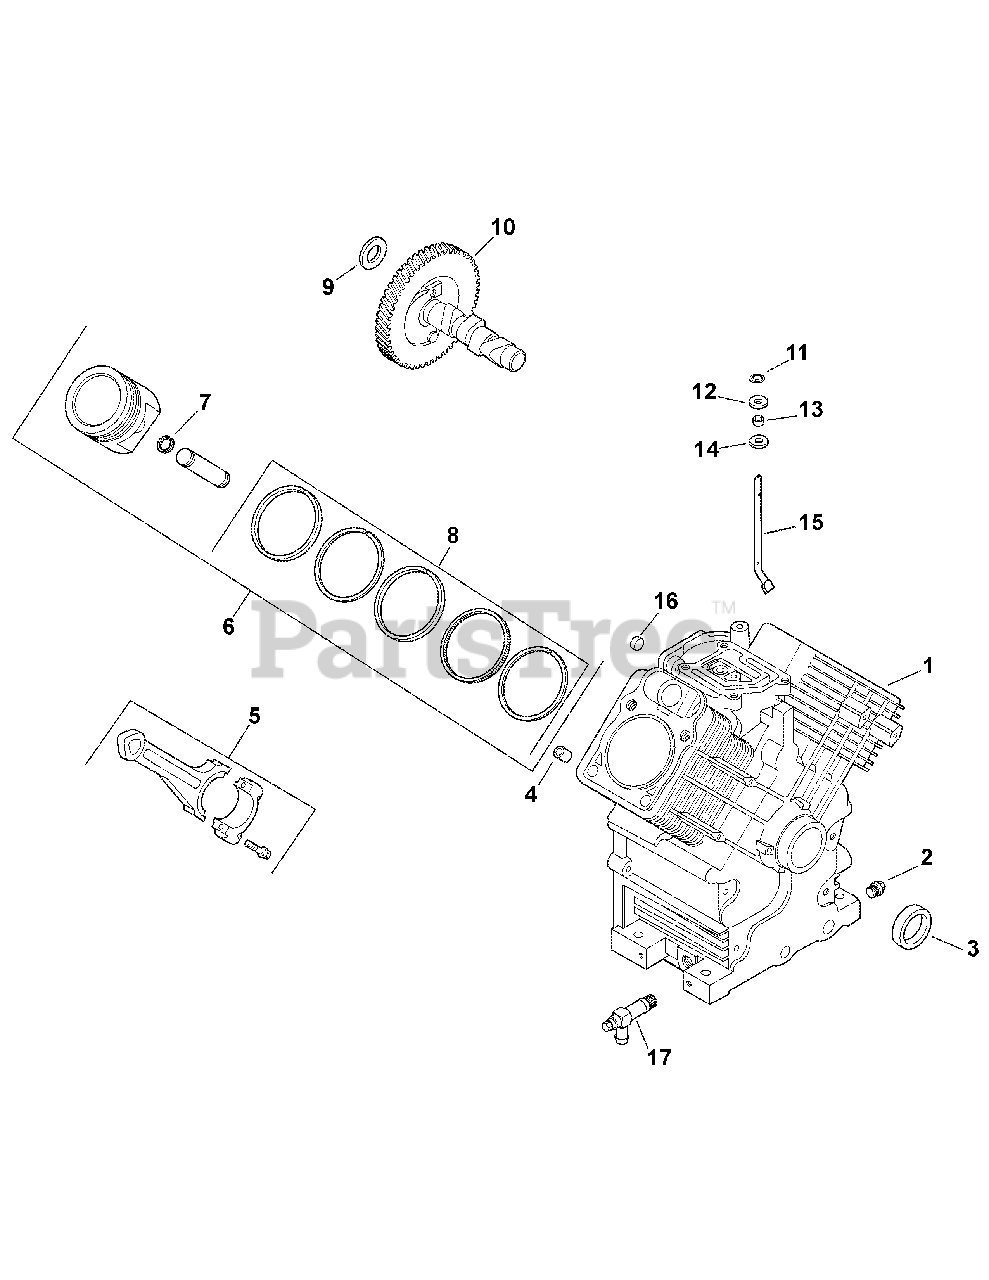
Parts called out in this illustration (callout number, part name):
1	Crankcase
1	Engine, Complete
2	Plug, sq. head 3/8" (2)
3	Seal, front oil
4	Pin, locating (6)
5	Connecting Rod (Std.) (2)
5	Connecting Rod (.25) (2)
6	Piston w/Ring Set (Std.) (2)
6	Piston w/Ring Set (.08) (2)
6	Piston w/Ring Set (.25) (2)
6	Piston w/Ring Set (.50) (2)
7	Retainer, piston pin (4)
8	Ring Set (Std. & .08) (2)
8	Ring Set (.25) (2)
8	Ring Set (.50) (2)
9	Shim, camshaft (A.R.) red
9	Shim, camshaft (A.R.) black
9	Shim, camshaft (A.R.) white
9	Shim, camshaft (A.R.) blue
9	Shim, camshaft - yellow
9	Shim, camshaft (A.R.) green
9	Shim, camshaft (A.R.) gray
10	Camshaft
11	Retainer, ring
12	Washer, plain 9 mm
13	Seal, governor cross shaft
14	Washer, plain 1/4"
15	Shaft, governor cross
17	Valve, oil drain
